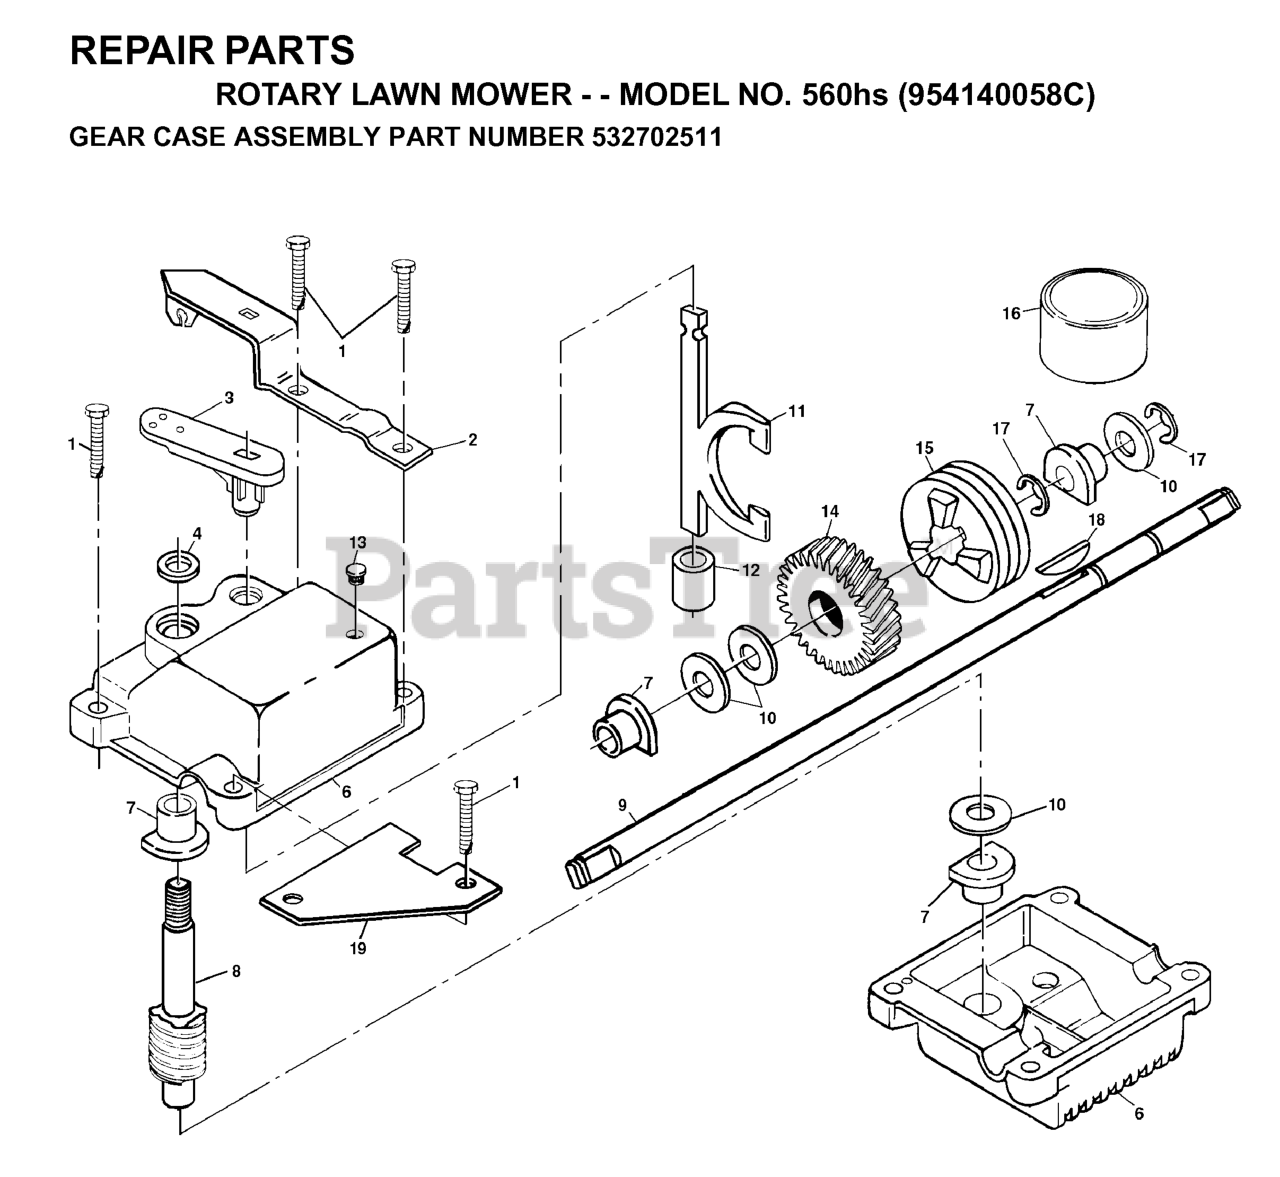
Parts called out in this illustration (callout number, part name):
1	SCREW
2	BRACKET
5	GROOVED PIN
8	WORM SHAFT
9	DRIVE SHAFT, 20-5/8"
10	THRUST WASHER
11	YOKE.VIBRATORY FINISH.
13	PLUG.AUGER.GEAR.BOX.SNOW
14	GEAR.HELICAL
15	CLUTCH JAW
16	GREASE
18	HI PRO KEY
19	BRACKET SPRING
